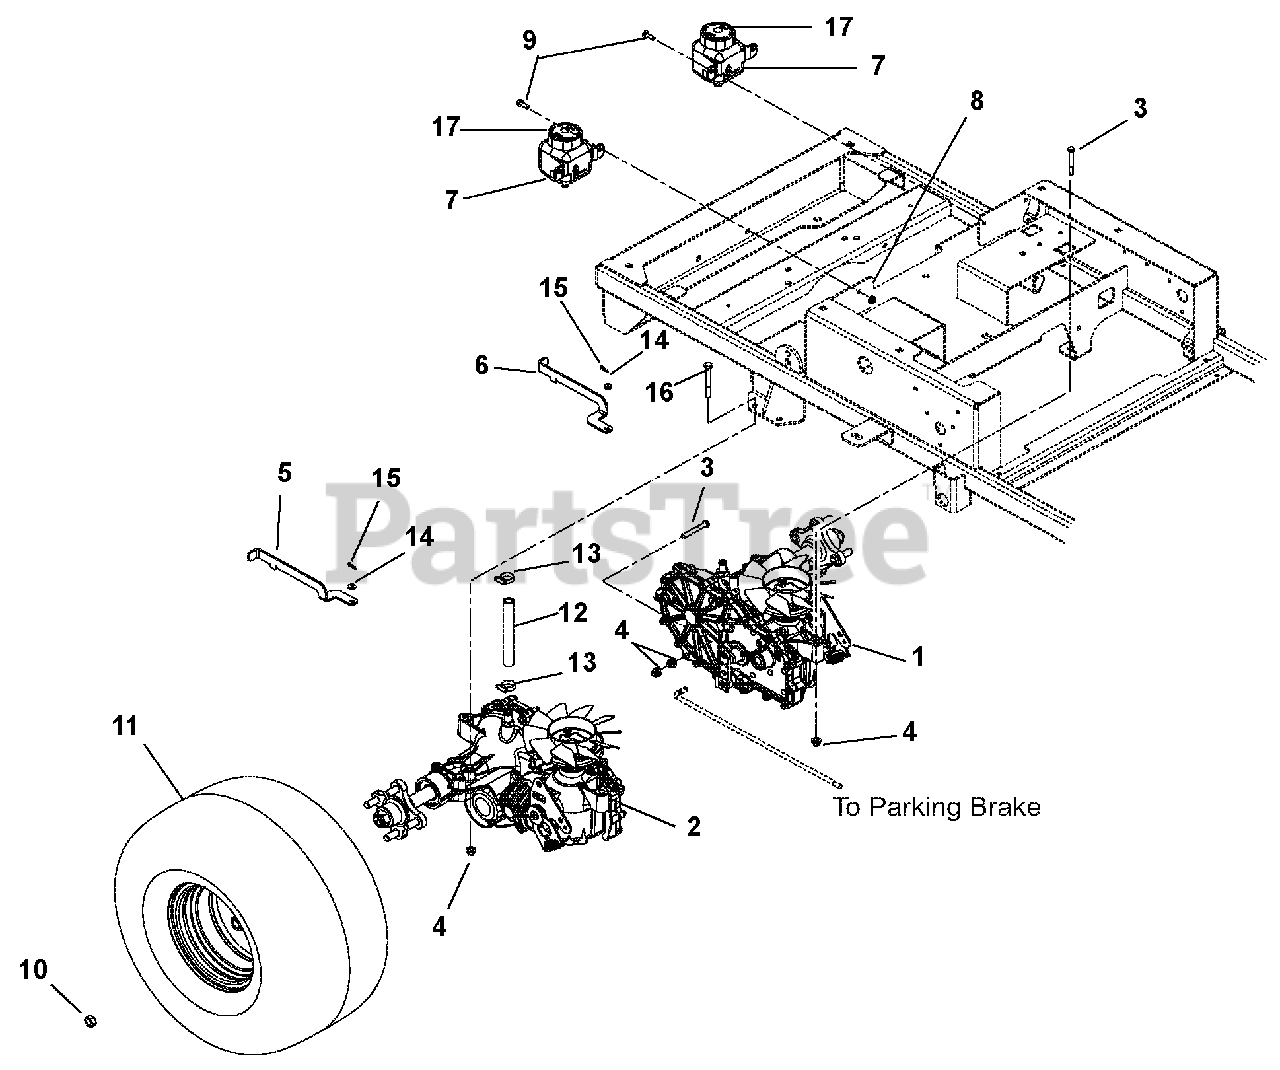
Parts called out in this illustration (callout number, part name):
1	TRANSAXLE, ZT2800 LH
2	TRANSAXLE, ZT2800 RH
3	BLT-HEX .31-18X2.25 GR5 YWZC
4	NUT-LK-NYL-FLG .31-18 YWZC
5	DUMP VALVE, RH
6	DUMP VALVE, LH
7	TANK, EXPANSION ZT2800
8	NUT-LK-TOP-FLG .25-20 YWZC
9	BLT-HEX .25-20X.75 GR5 YWZC
10	WHEEL NUT .500-20 YZ
11	TIRE/WHEEL ASSY, 20X10.0-8 CTR
12	HOSE, OIL RESERVOIR
13	CLAMP,.88 DIA. HOSE
14	WSHR-FL-STL .265X.50X.087YWZC
15	PIN-HAIR INT .06X.18X.77
16	BLT-HEX .31-18X2.75 GR5 YWZC
17	CAP, HYDRO RESERVOIR REPLAC.
